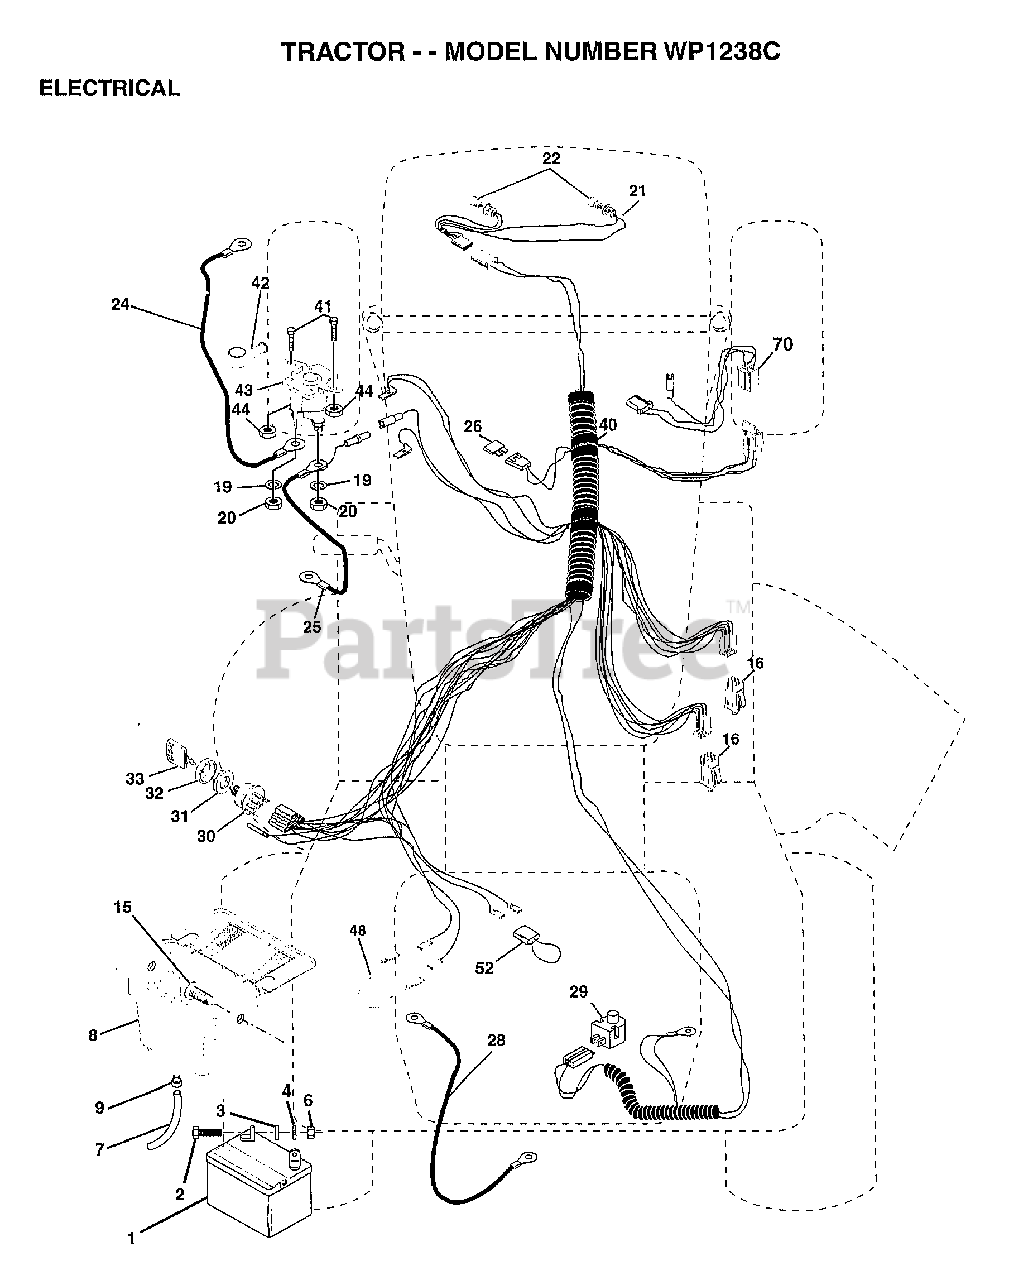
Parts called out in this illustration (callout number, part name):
2	BOLT LT
3	WASHER
4	LOCKWASHER
7	TUBE T
8	"CASE,BATTERY.MECH"
9	HOSE CLAMP T
15	FASTNER.SNAP-IN
16	SWITCH INTERLOCK
20	NUT
21	"HARNESS,LIGHT SOC"
22	HEADLAMP BULB
24	"CABLE T, BATTERY"
25	CABLE.BTRY.6GA.RD
26	FUSE HYT
28	CABLE T
29	SWITCH SEAT
30	SWITCH IGN 4POS
31	NUT IGNITION
32	COVER KEY SWITCH
33	KEY
40	HARNESS-IGNITION
41	BOLT HXHD FIN
44	NUT HXKEP 1/4X20
48	ADAPTER AMMETER
52	PROTECTION LOOP
70	HARNESS ENG DUAL
